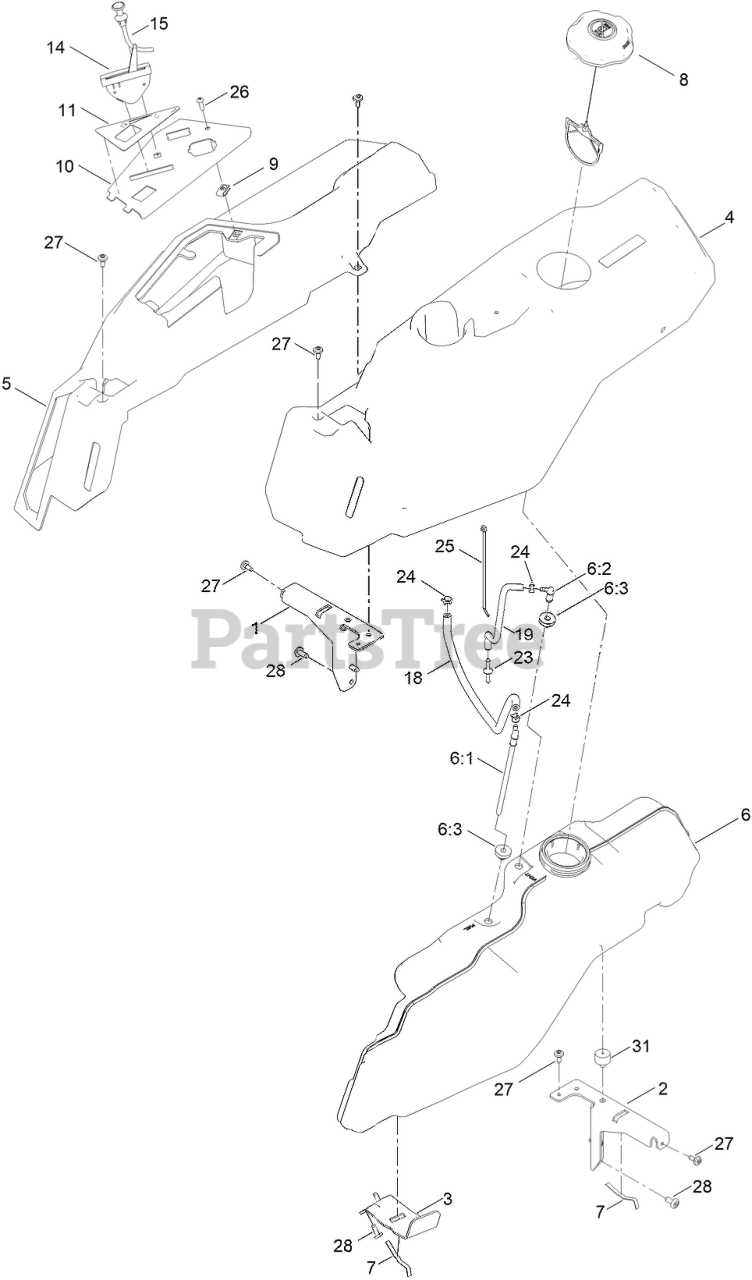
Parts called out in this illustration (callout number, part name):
1	SUPPORT-POD, RH
2	SUPPORT-POD, LH
3	SUPPORT-TANK, FUEL
4	POD-LH
5	POD-RH
6	FUEL TANK ASM
6:1	CONNECTOR-ELBOW, 90 DEG
6:2	FITTING-PLASTIC
6:3	BUSHING
7	SPRING
8	CAP-FUEL, RATCHETING
10	PANEL - CONTROL
11	DECAL-PANEL CONTROL
14	CABLE-THROTTLE
15	CABLE-CHOKE
18	HOSE-FUEL
19	HOSE-FUEL
23	ADAPTOR-ORIFICE
24	CLAMP-HOSE
25	TIE-CABLE
26	SCREW-PRH
27	SCREW-SHOULDER
31	BUMPER-GROMMET
